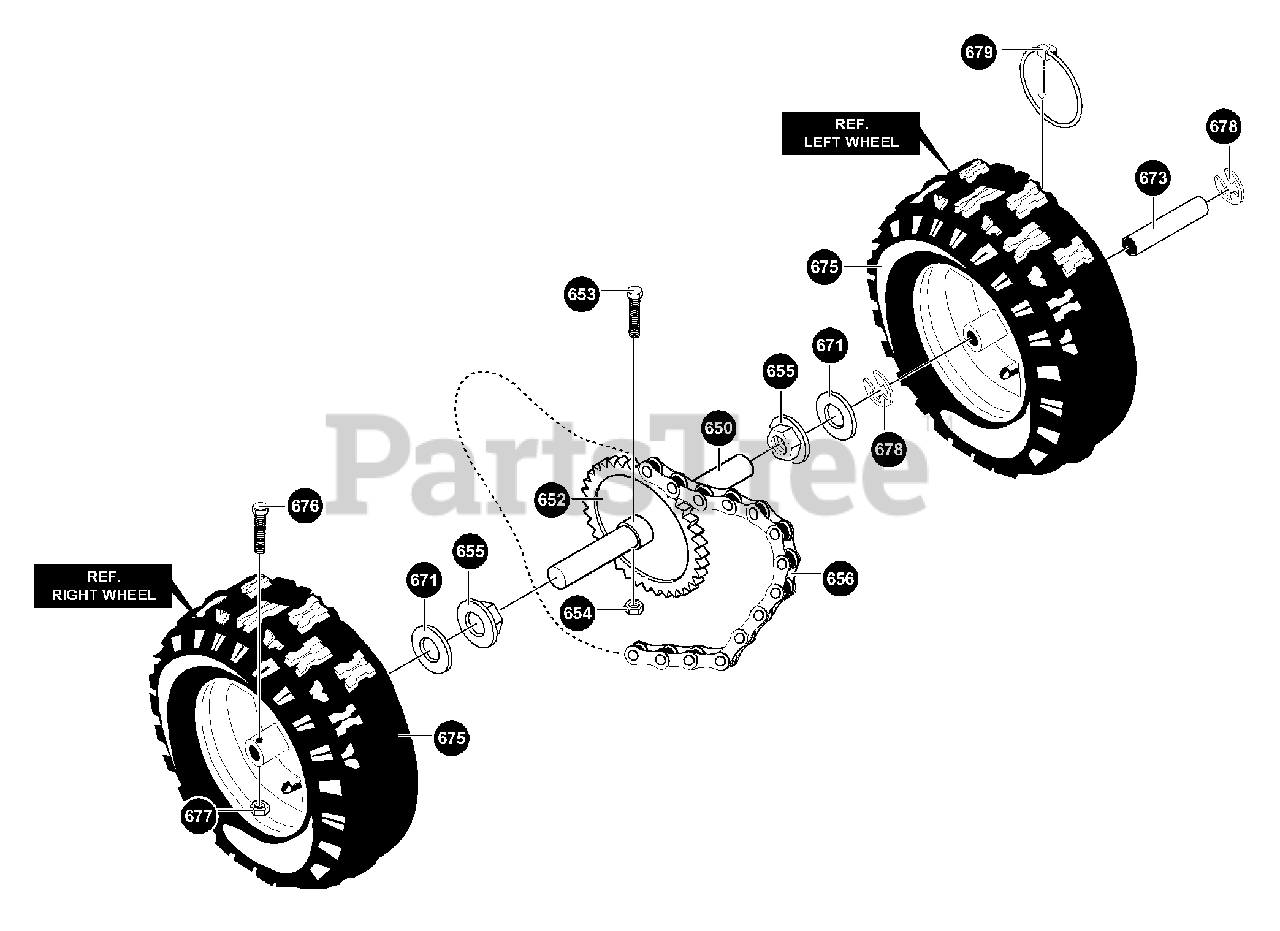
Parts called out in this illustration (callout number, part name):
650	SHAFT, AXLE
652	SPRKT & HUB
653	SCREW, 1/4-20X2.25
654	NUT, 1/4-20
656	CHAIN, ROLLER
671	FLATWASHER .765X1.12X.06
673	BUSHING, WHEEL
675	TIRE & RIM
676	SCREW, 1/4-20X1.75
677	NUT, 1/4-20
679	PIN, KLIK .25 X 1.38 DIA
